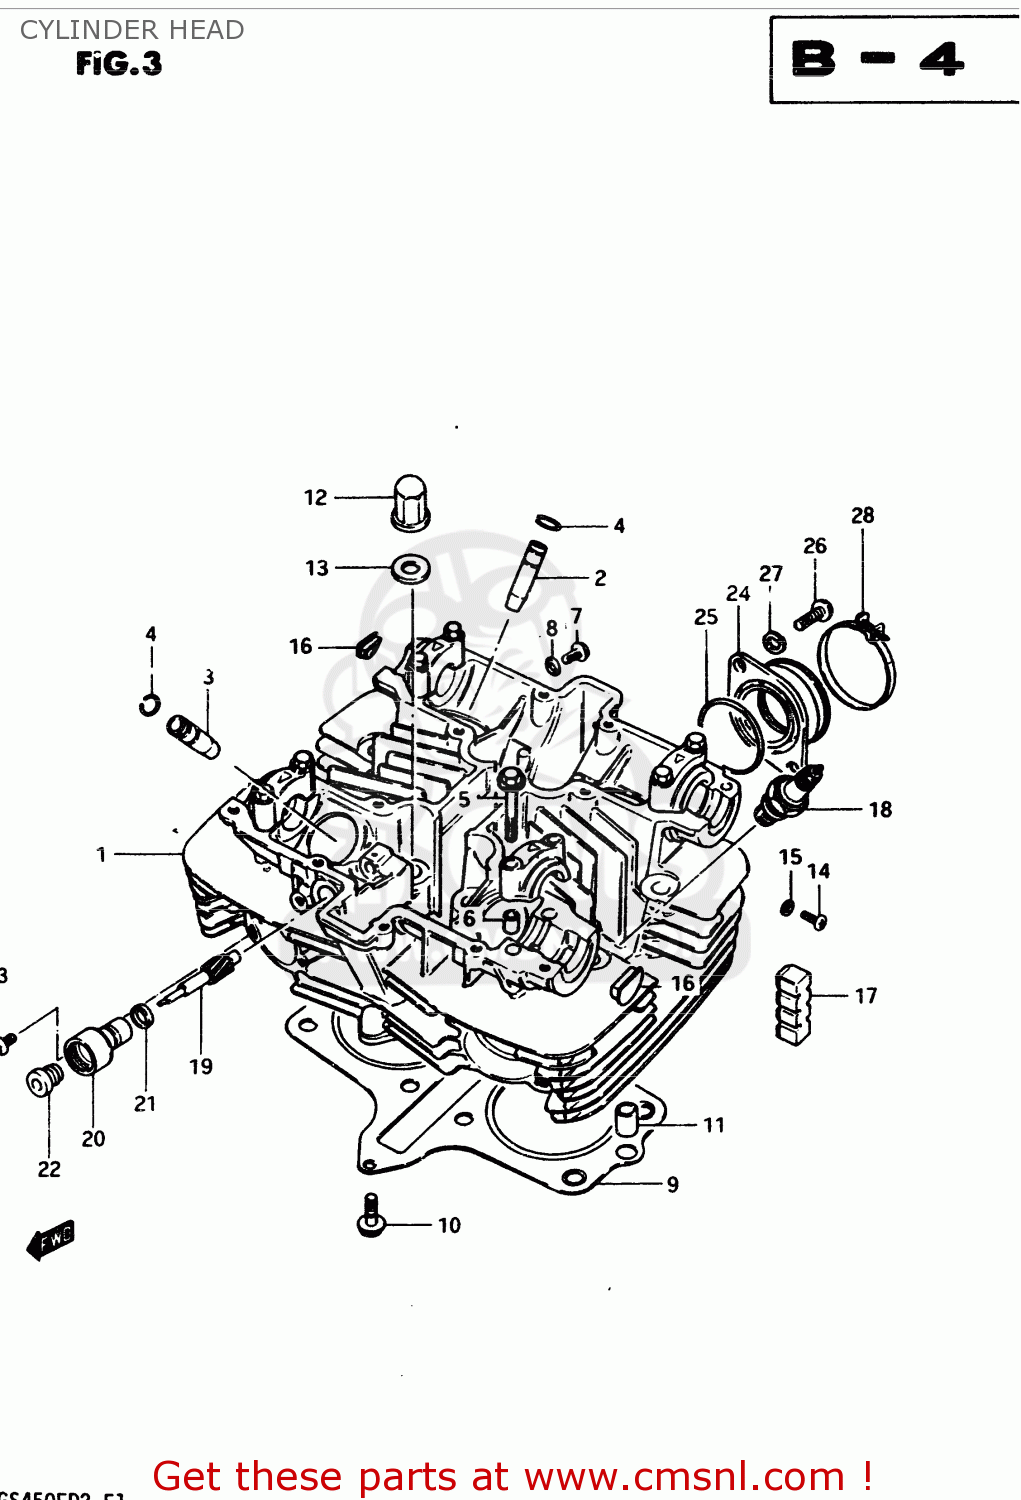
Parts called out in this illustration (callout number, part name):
1	HEAD SET,CYLINDER
2	GUIDE,INTAKE VALVE
3	GUIDE,EXHAUST VALVE
4	RING,SNAP
5	BOLT(6X39)
6	PIN(6.2X8X11)
7	BOLT
8	WASHER
9	GASKET,CYLINDER HEAD (MCA)
10	BOLT
11	PIN
12	NUT
13	GASKET(10.5X22X2) (NAS)
14	SCREW
15	GASKET(5.3X9.3X1.2) (NAS)
16	PLUG
17	PAD,CYLINDER
18	PLUG,SPARK
19	GEAR,TACHOMETER DRIVEN
20	SLEEVE,TACHOMETER DRIVE GEAR
21	SEAL,TACHOMETER DRIVEN
22	SEAL,OIL(5X12X8)
23	SCREW(5X12)
24	PIPE,INTAKE
25	O-RING (D:2.4 ID:39.7)
26	SCREW
27	LOCK WASHER
28	CLAMP
